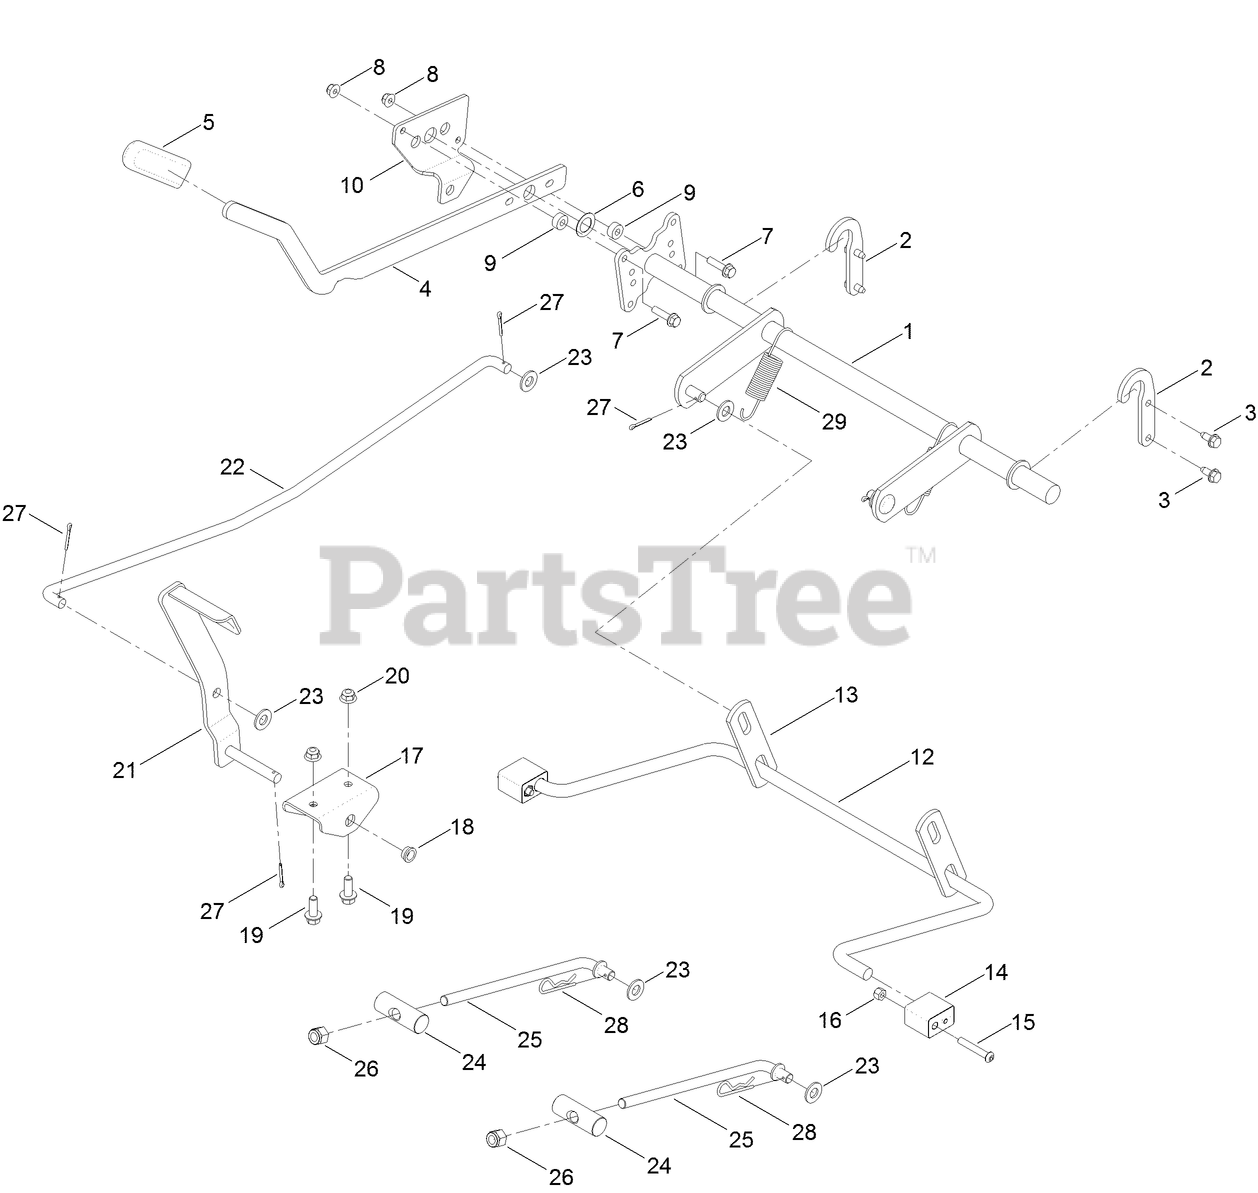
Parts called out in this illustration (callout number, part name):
1	DECK LIFT ASM
2	BRACKET-LIFT
3	SCREW-HWHTF
4	LEVER-LIFT
5	GRIP-LEVER
6	WASHER-THRUST
7	SCREW-HHF
8	NUT-HF, NI
9	SPACER
10	PLATE-FOOTLIFT
12	ARM-LIFT, REAR (WIDE)
13	LINK-LIFT
14	BLOCK-PIVOT
15	SCREW-HSBH
16	NUT-LOCK, NI
17	BRACKET-FOOTLIFT
18	BUSHING-FLANGE
19	SCREW-HHF
20	NUT-HF, NI
21	PEDAL ASM
22	ROD-FOOTLIFT
23	WASHER-FLAT
24	PIN-PIVOT
25	ROD-MOUNT, DECK
26	NUT-HEX
27	PIN-COTTER
28	PIN-COTTER
29	SPRING, EXTENSION
